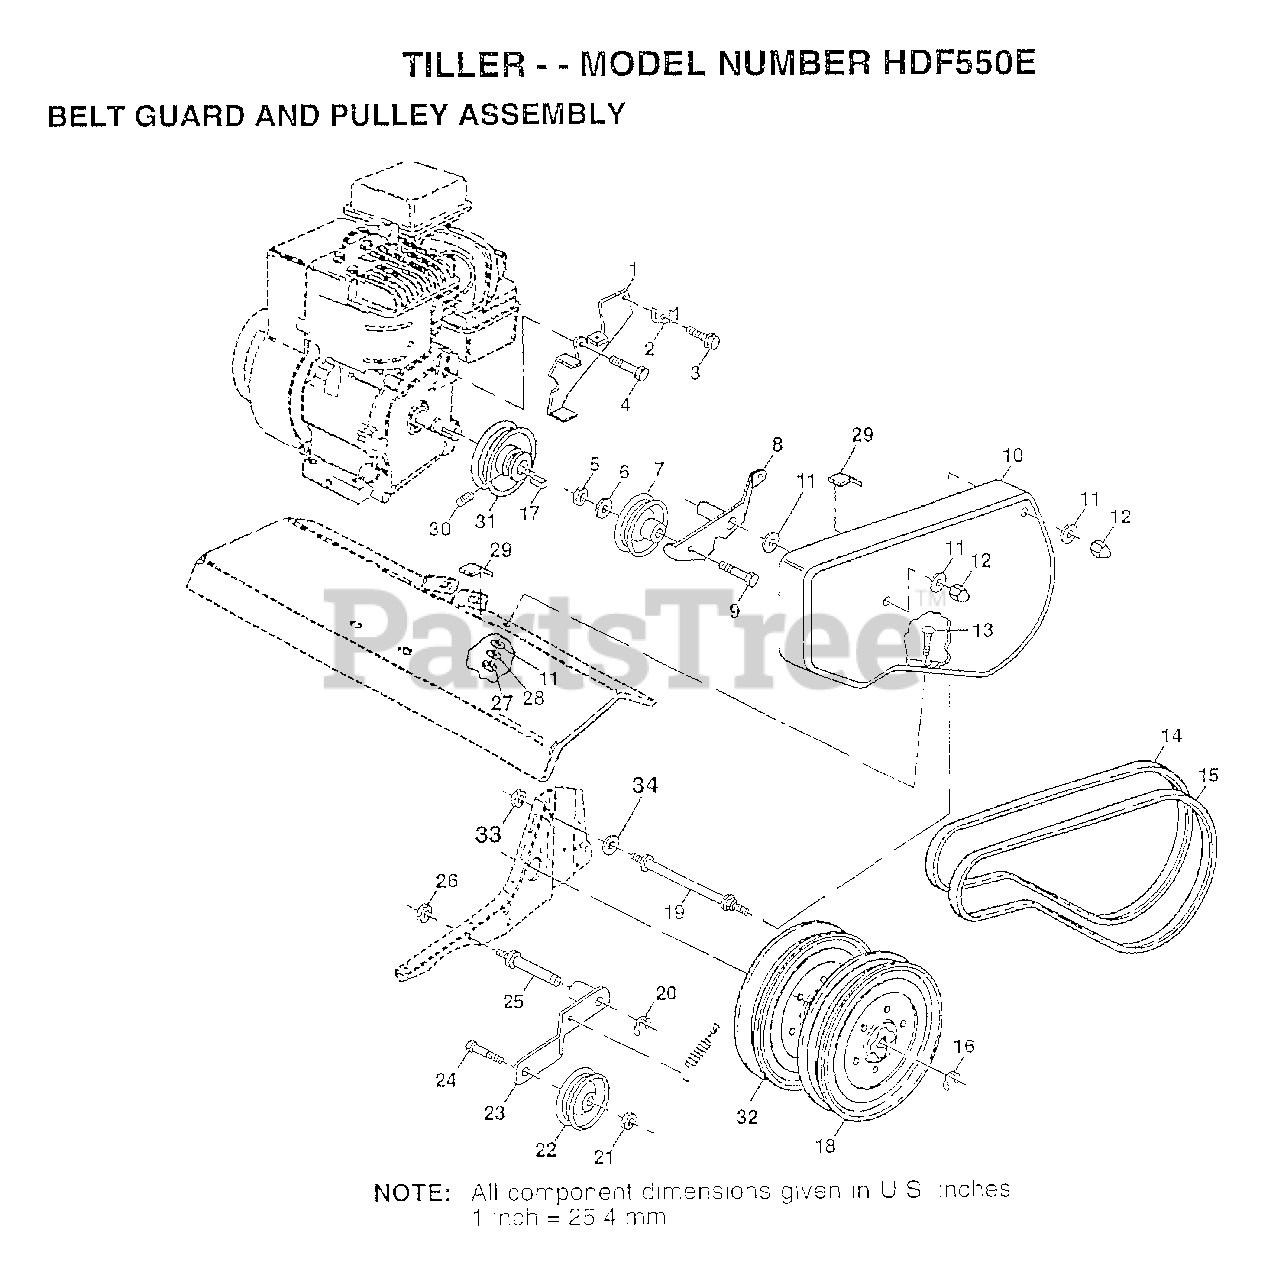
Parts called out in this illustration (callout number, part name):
1	ASM.BRKT.BELT.GRD
2	CONDIUT CLIP T
4	BOLT.HEX.HEAD
5	NUT.HEX.3/8-16UNC
6	WASHER
7	PULLEY W/SPACER
8	ARM.ASM.REV.IDLER
10	GUARD.PNT.BELT.MS-428
11	WASHER
12	NUT-CAP TI
13	BOLT T
14	BELT-V
17	KEY T
18	"SHEAVE,TRANS.""D"""
19	BOLT TI
20	KLIP RING TI
21	NUT
23	IDLER ARM TI
25	SHAFT IDLER TI
26	JAM NUT TI
28	LOCKWASHER
29	PAD IDLER TI
30	SET SCREW
31	ENGINE PULLEY TI
32	SHEAVE.TRANS
33	NUT
34	WASHER
